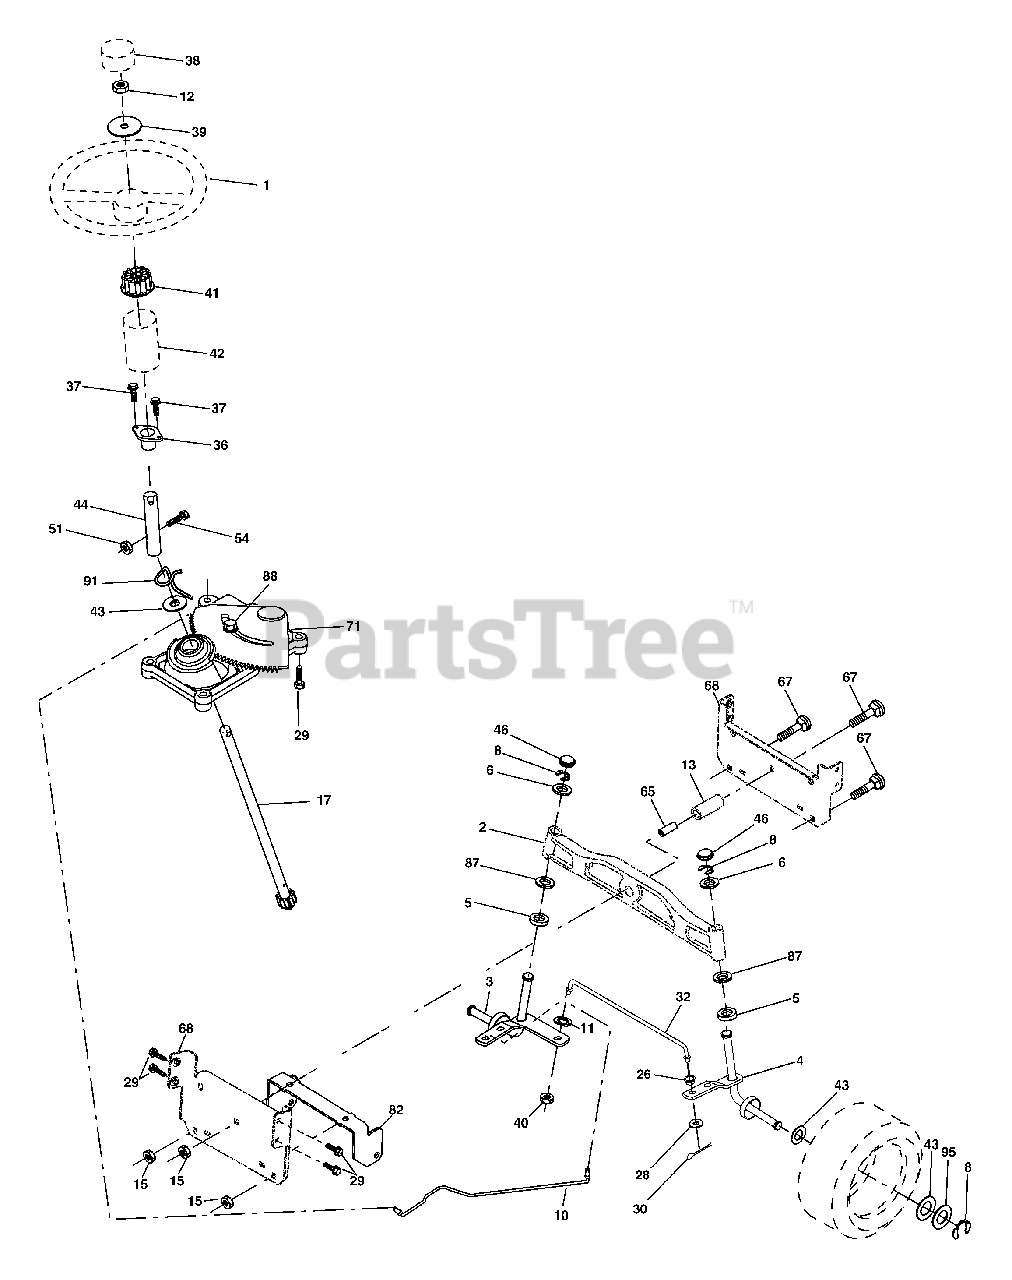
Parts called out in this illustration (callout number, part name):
1	Wheel Steering
2	Axle Asm
3	Spindle Asm LH
4	Spindle Asm RH
5	Bearing Race Thrust Harden
6	Washer 25/32 x 1-5/8 x 16 Ga.
8	Ring Klip #t5304-75
11	Washer Lock Hvy Hlcl Spr 3/8
12	Nut Hex Jam Toplock 1/2-20 unf
13	Spacer Brg Axle Front
15	Nut Hex Flange Lock
17	Shaft Asm Strg
26	Bushing Link Drag Blk LR
28	Washer 13/32 x 7/8 X 16 Ga.
29	Screw 3/8-16x3/4
30	Pin Cotter 1/8 x 3/4 Cad
32	Rod Tie Wire Form 19 75 Mech
36	Bushing Strg
38	Cap Wheel Steering
39	Washer 9/16 x 1-1/2 11 Ga.
40	Nut Crownlock 3/8-24
41	Adaptor Wheel Strg
42	Boot Steering Shaft
43	Washer 25/32 x 1 1/4 X 16 Ga.
44	Extension Steering Shaft LR/LT
46	Cap Spindle Fr Top Blk
51	Nut Crownlock 1/4-28
54	Bolt Hex 1/4-28 unf x 1-1/4 Gr. 8
65	Spacer Brace Axle
67	Bolt Rdhd Sq 3/8-16 x 2-1/4
68	Axle, Brace
71	Steering Asm
82	Bracket Susp Chassis Front
87	Washer Flat .781 x 1 1/2 x .14
88	Bolt Shoulder 7/16-20
91	Clip Steering
95	Washer Harden .793 x 1.637 x .060
